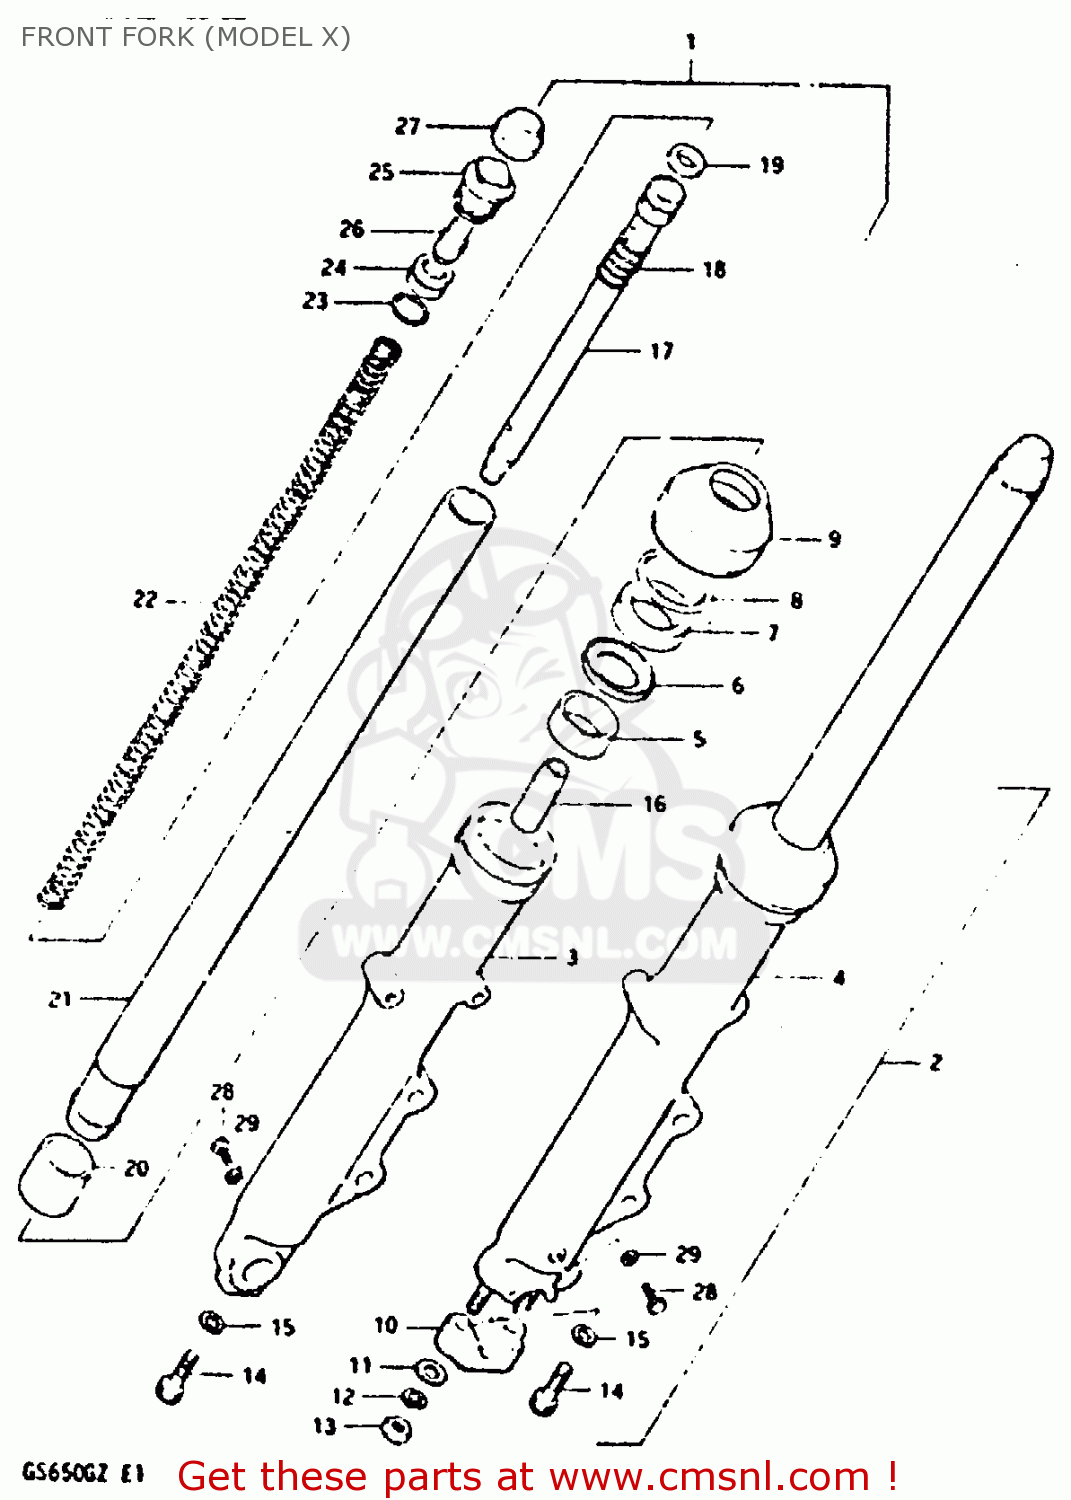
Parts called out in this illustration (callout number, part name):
1	DAMPER ASSY, RH
2	DAMPER ASSY, LH
3	OUTER TUBE RH
4	OUTER TUBE LH
5	GUIDE,FORK INNER TUBE
6	SPACER,SEAL
7	OIL SEAL,FRONT FORK
8	RING, STOPPER
9	BOOT
10	HOLDER,AXLE
11	WASHER
12	LOCK WASHER
13	NUT
14	BOLT(8X27)
15	GASKET (NAS)
16	PIECE,OIL LOCK
17	CYLINDER
18	SPRING,FORK REBOUND
19	RING,PISTON
20	PISTON
21	INNER TUBE
22	SPRING
23	O RING
24	SEAT,FRONT FORK SPRING
25	BOLT
26	ADJUSTER, SPRING
27	CAP
28	BOLT(6X8)
29	GASKET,DRAIN,PLUG (NAS)
